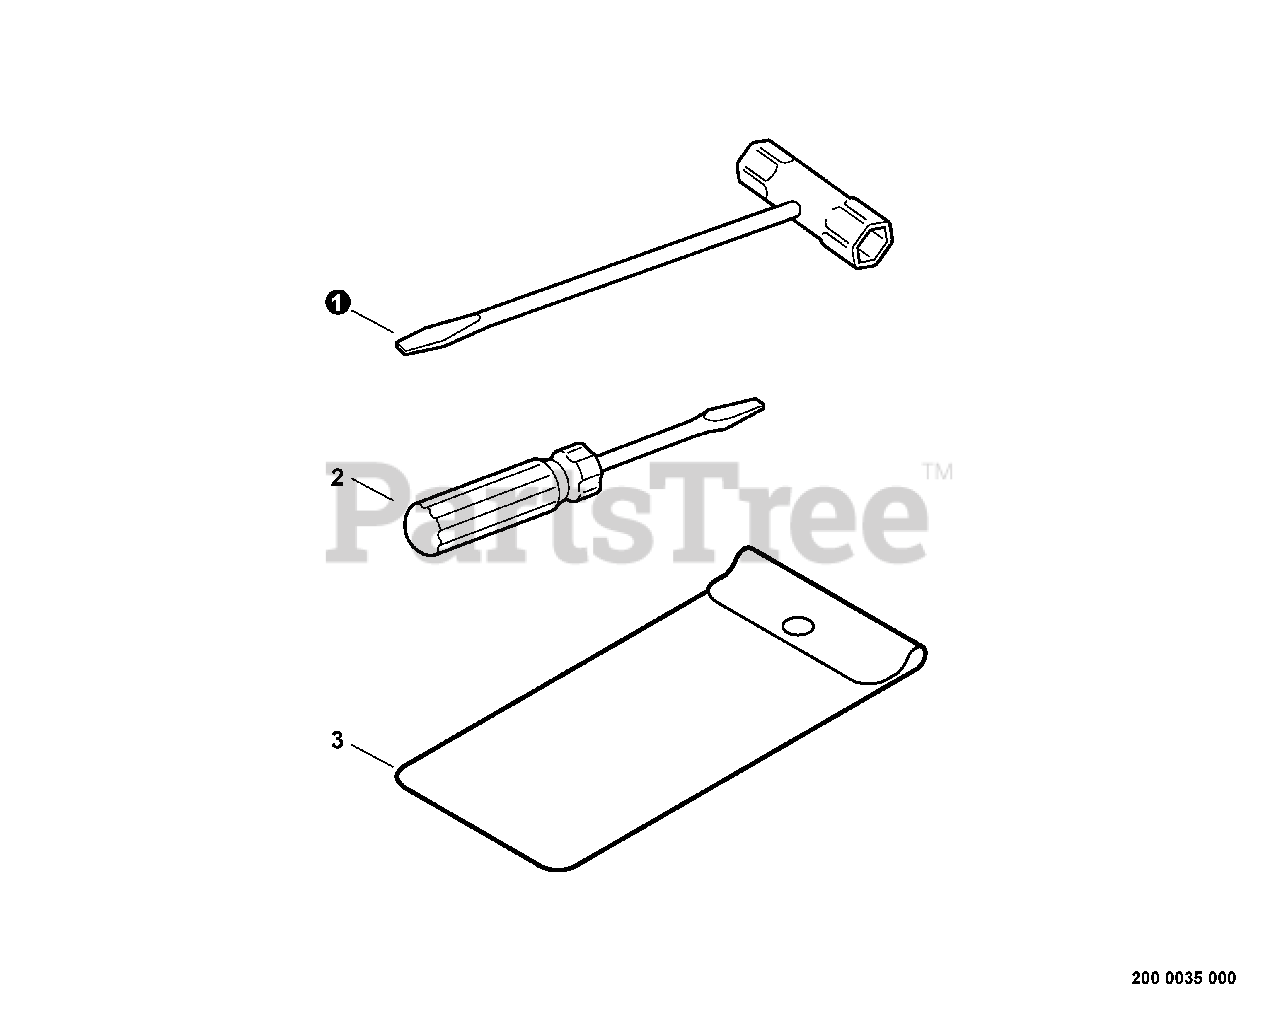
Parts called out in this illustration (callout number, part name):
1	T-WRENCH - 13X19mm
2	SCREWDRIVER
3	BAG, TOOL
